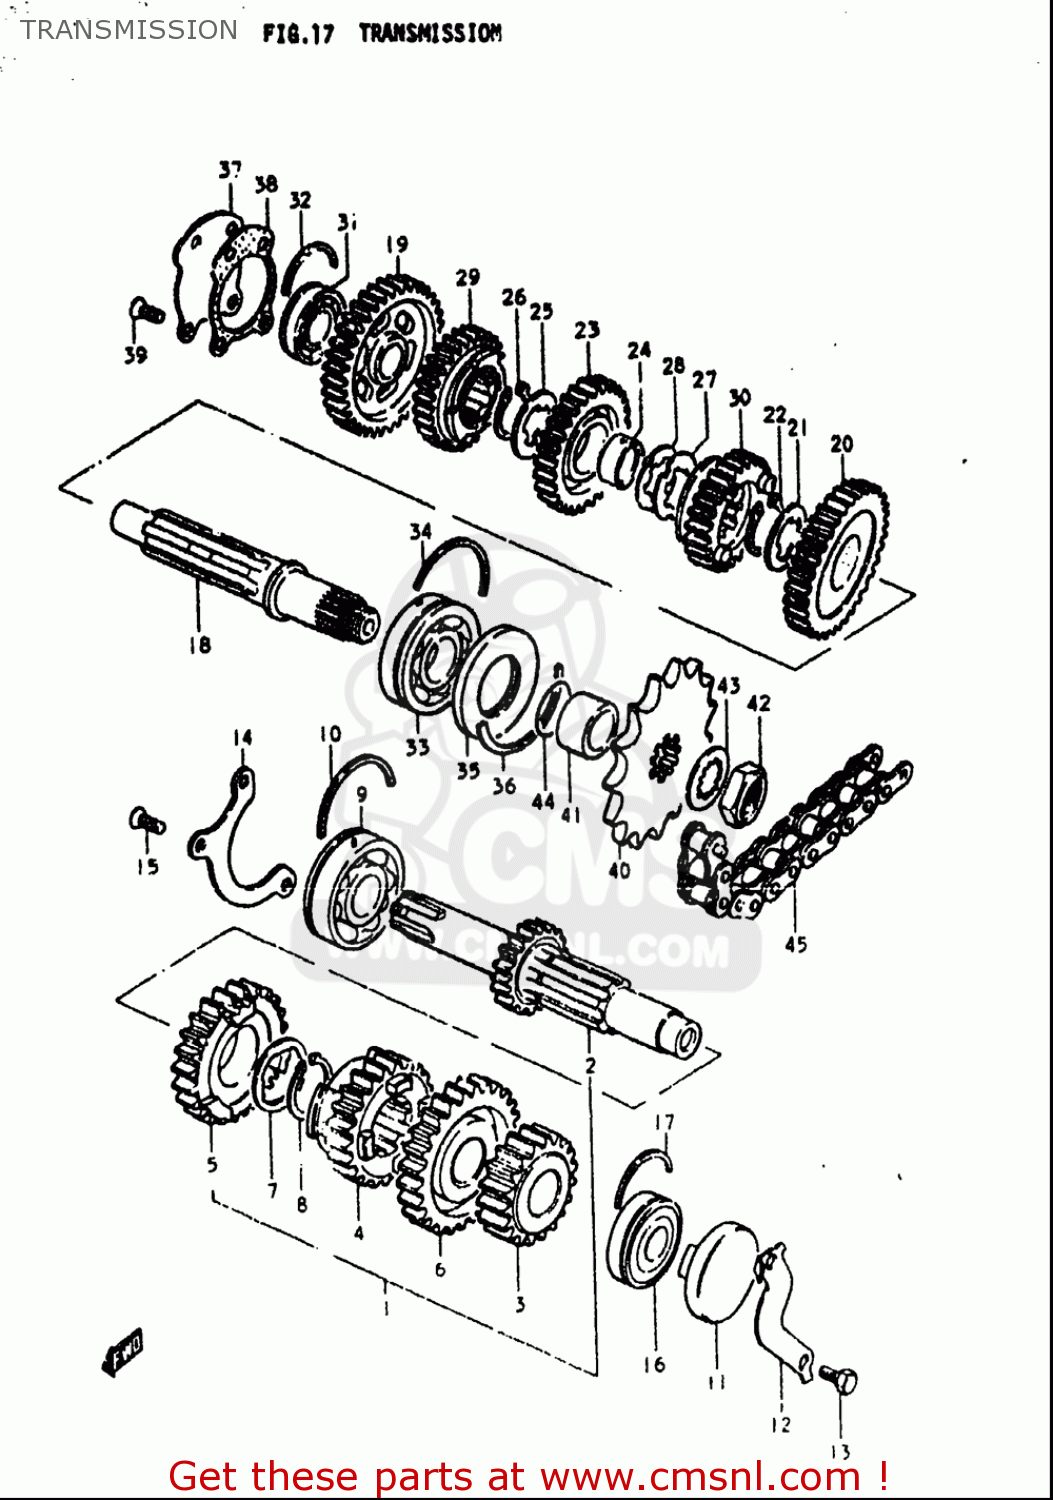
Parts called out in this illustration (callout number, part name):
6	GEAR,FIFTH DRIVE
7	WASHER,LOCK
8	CIRCLIP
9	BEARING(25X62X17)
10	C RING
11	PLUG
12	RETAINER,CL PUSH ROD OIL SEAL
13	BOLT
14	RETAINER,CNTR SHAFT BEARING
15	SCREW
16	BEARING(20X47X14)
17	C RING
21	WASHER,LOCK
22	CIRCLIP
24	BUSH,3RD DRIVEN GEAR
25	WASHER,LOCK
26	CIRCLIP
27	WASHER,LOCK
28	WASHER
31	BEARING(20X47X14)
32	C RING
33	BEARING(25X62X17)
34	C RING
35	SEAL,OIL(32X62X7)
36	C RING
37	PLATE,DRIVE SHAFT
38	GASKET,DRIVE SHAFT PLATE (NAS)
39	SCREW
40	SPROCKET,ENGINE(NT:15)
41	SPACER(25X32X18.6)
42	NUT
43	WASHER,LOCK
44	O RING(D:1,ID:24.5)
45	CHAIN,DRIVE(DID630YL,96LE)
